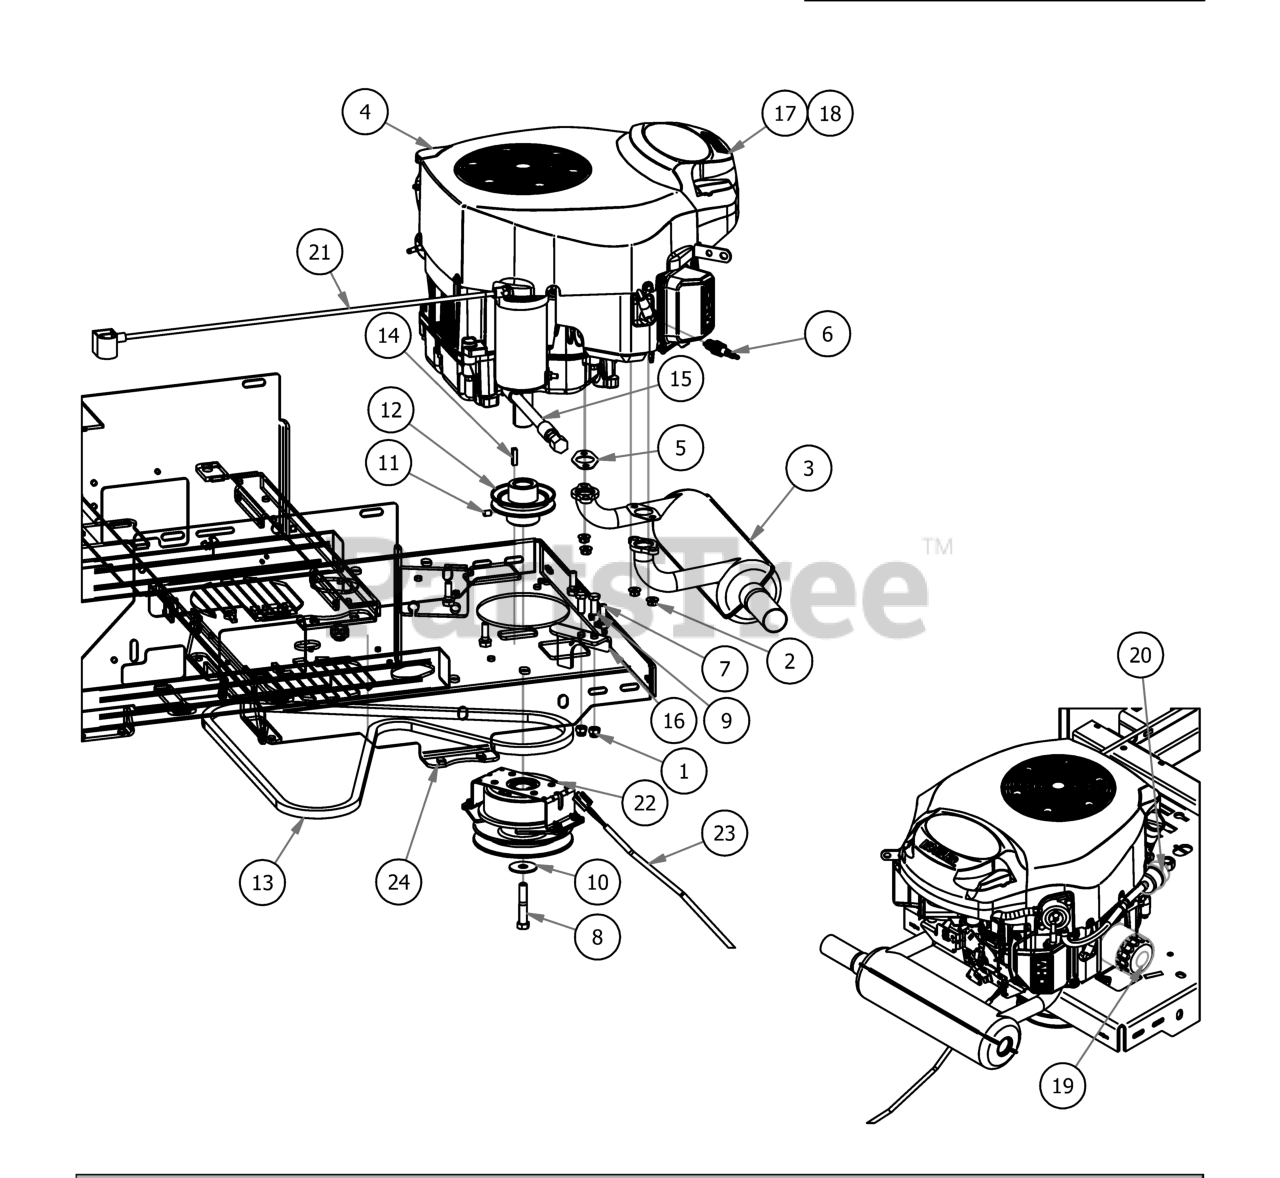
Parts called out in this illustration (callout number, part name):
1	3/8-16 NYLON INSERT LOCKNUT ZINC
2	M8 Flange Nut for Kohler Exhaust
3	Kohler Muffler
4	Kohler MZ Magnum 740cc
5	Exhaust Gasket
6	Spark Plug
7	3/8 x 1 1/8 bolt
8	7/16"-20 x 2.5" Hex Bolt Gr. 8
9	3/8-16 X 1 GR 5 Hex Bolts Zinc
10	1/2" Belleville Washer
11	3/8" Set Screw
12	3-3/4" Motor Pulley
14	1/4 X 1 SQ MACHINERY KEY 1018 STL PLN
15	Oil drain Hose
16	2017 MZ Clutch Stop
17	Kohler KT740 Precleaner
18	Kohler KT740 Air Element
19	725 Kohler Oil Filter
20	Universal Inline Fuel Filter
21	24" Black Ground Cable
23	Clutch Pigtail
24	2017 MZ/ZT 54"-60" Frame
